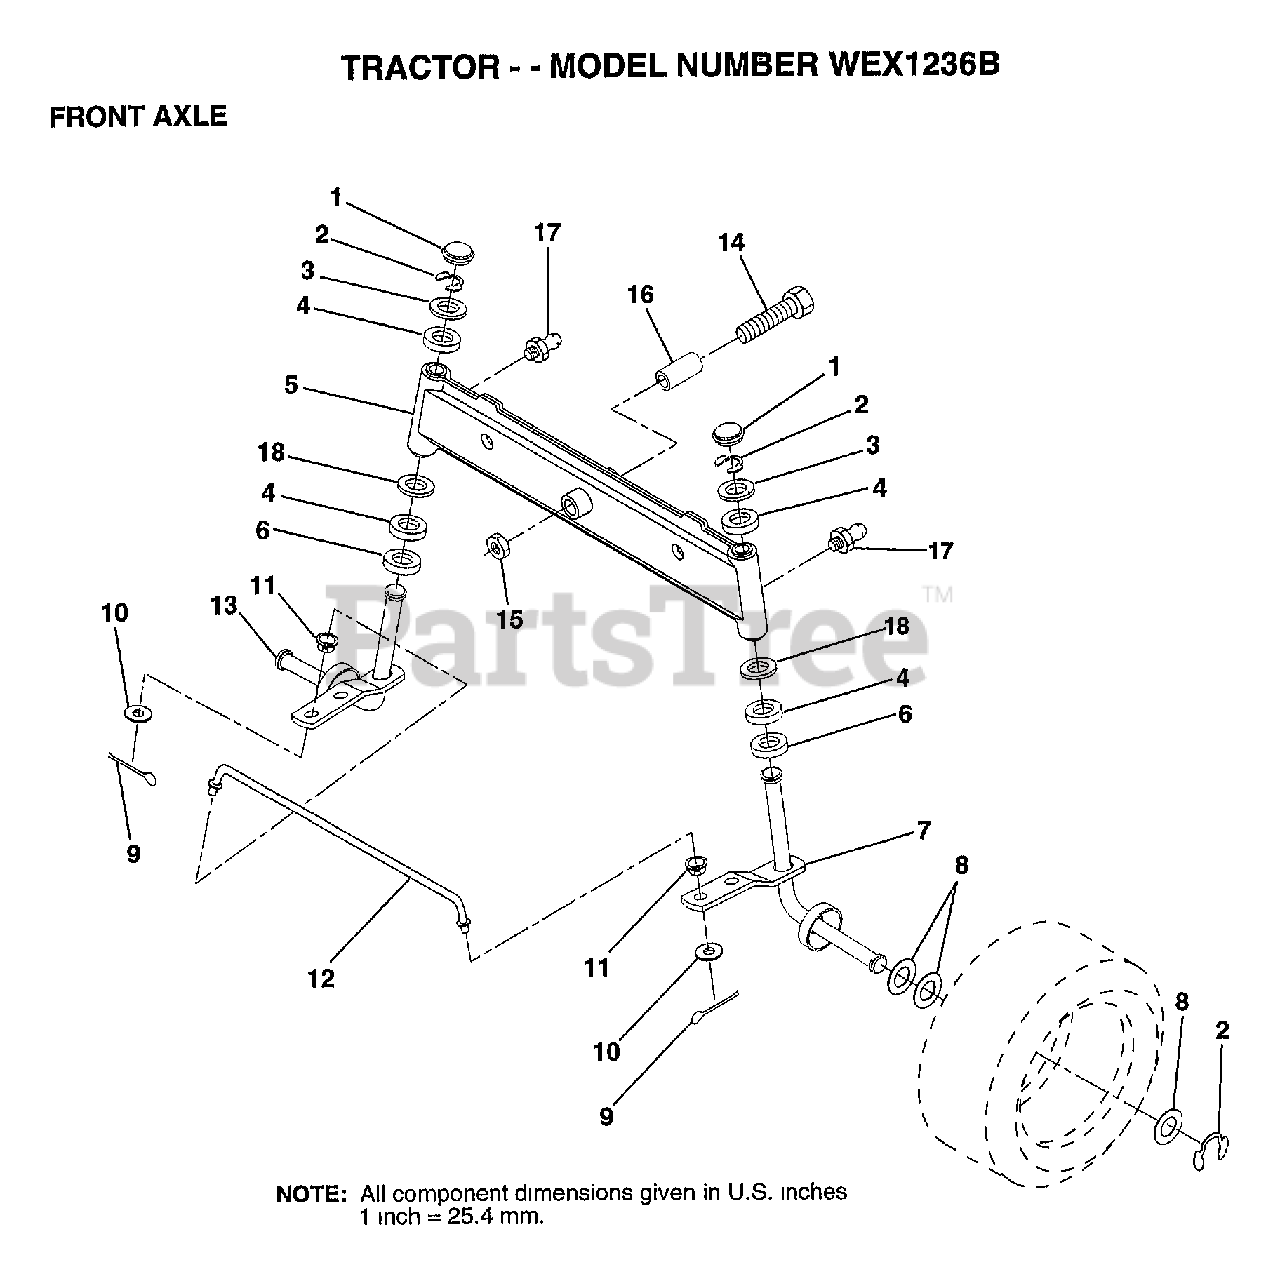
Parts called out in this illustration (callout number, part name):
1	CAP
2	RING
3	WASHER
4	COL. SRTG. BEAR.
5	AXLE ASM FRONT
6	WASHER .T
7	SPINDLE.ASSY.RH
8	WASHER
9	COTTER PIN
10	WASHER
11	BUSHING.DRAGLINK
12	TIE ROD
13	SPINDLE.ASSY.LH
14	BOLT HEX 5/8-11
15	"NUT-LOC,FLANGE LT"
16	BEARING
17	ZERK M
18	WASHER
